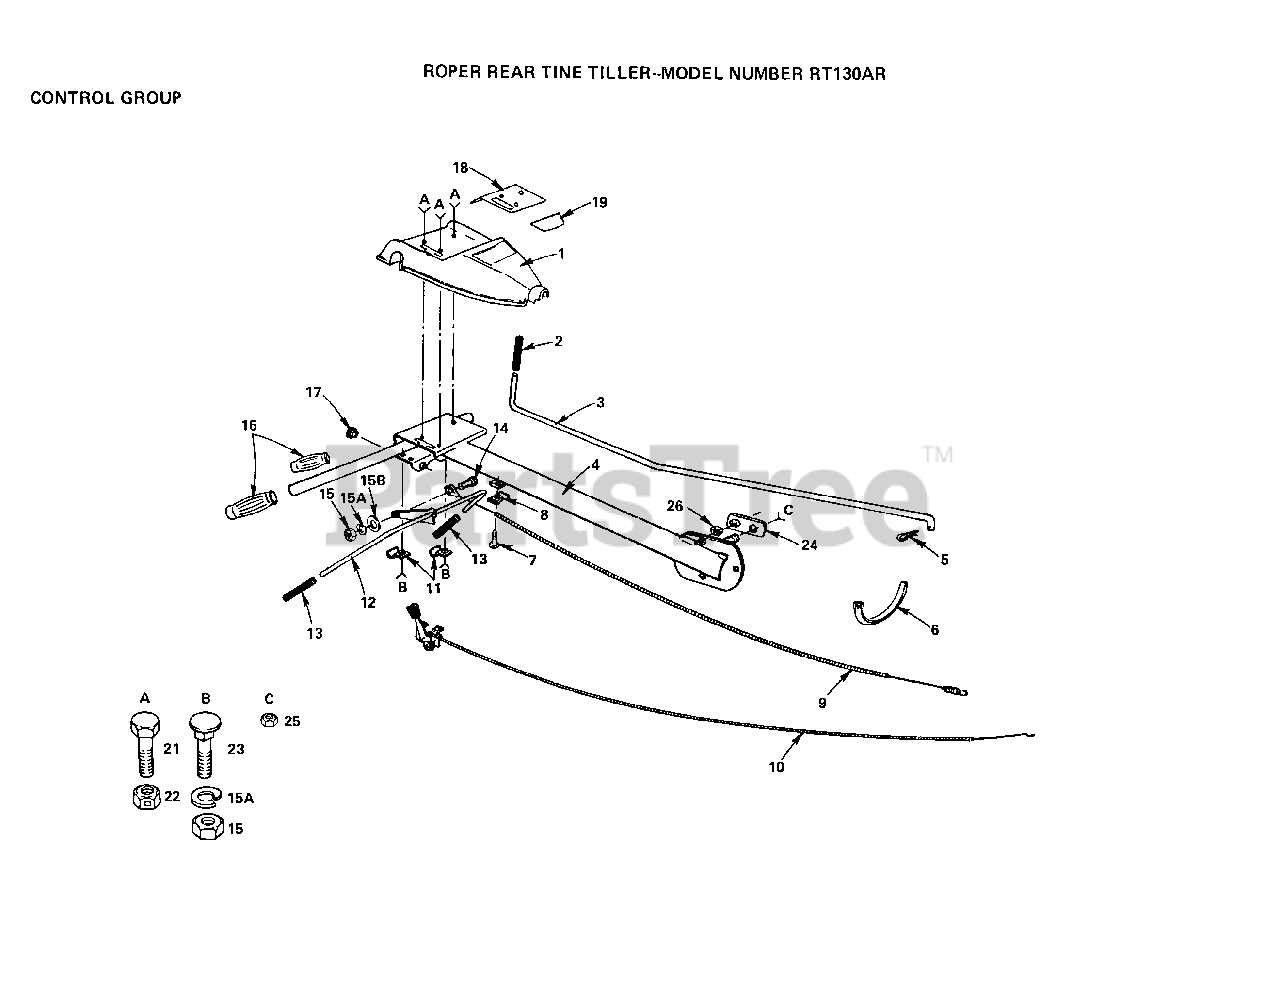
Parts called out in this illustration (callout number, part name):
1	PANEL - CONTROL
2	GRIP TI
5	RETAINER M
6	TIE CABLE CRT
7	SCREW TI
8	CONDIUT CLIP T
9	CABLE.CLUTCH.CRT
13	GRIP BAR CRT
14	SHOULDER BOLT ST
15A	LOCKWASHER
15B	WASHER
17	GROMMET TI
19	DECAL - CONTROL PANEL
23	BOLT
24	"NUT, LOCK CRT"
25	LOCKNUT
26	NUT FLANGE CRT
